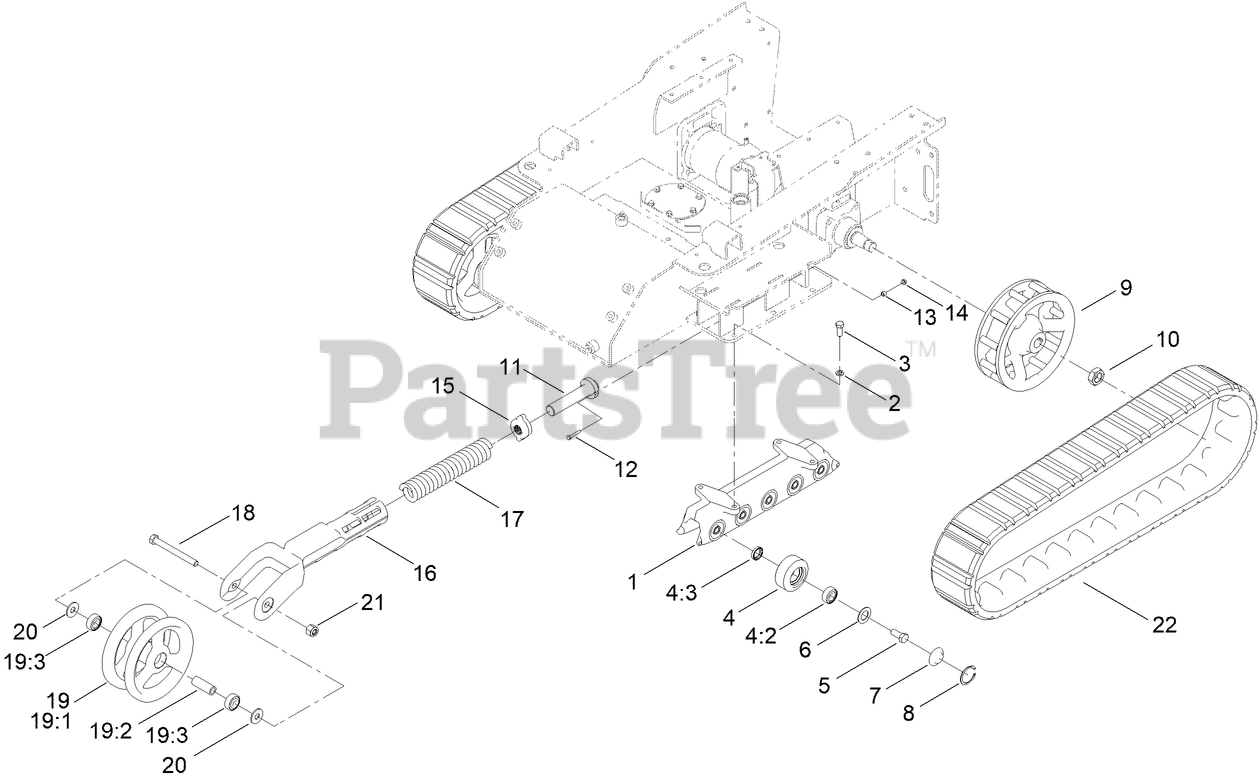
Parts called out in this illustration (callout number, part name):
1	GUIDE-TRACK, TX NARROW
2	WASHER-LOCK
3	SCREW-HH
4	ROAD WHEEL ASM
4:2	BEARING-BALL
4:3	SEAL-OIL
5	SCREW-HH
6	GASKET-BOGIE
7	CAP-WHEEL, BEARING
8	RING-SNAP, INTERNAL
9	WHEEL-DRIVE
10	NUT-HEX
11	BOLT-TENSIONER
12	SCREW-HH
13	SPACER
14	NUT-HHF
15	BLOCK-TENSIONER
16	ARM-TENSIONER
17	SPRING-COMPRESSION
18	SCREW-HH
19	TENSIONER WHEEL ASM
19:1	WHEEL-TENSIONER
19:2	SPACER-WHEEL, TENSIONER
19:3	BEARING-BALL
20	WASHER-FLAT
21	NUT-HEX
